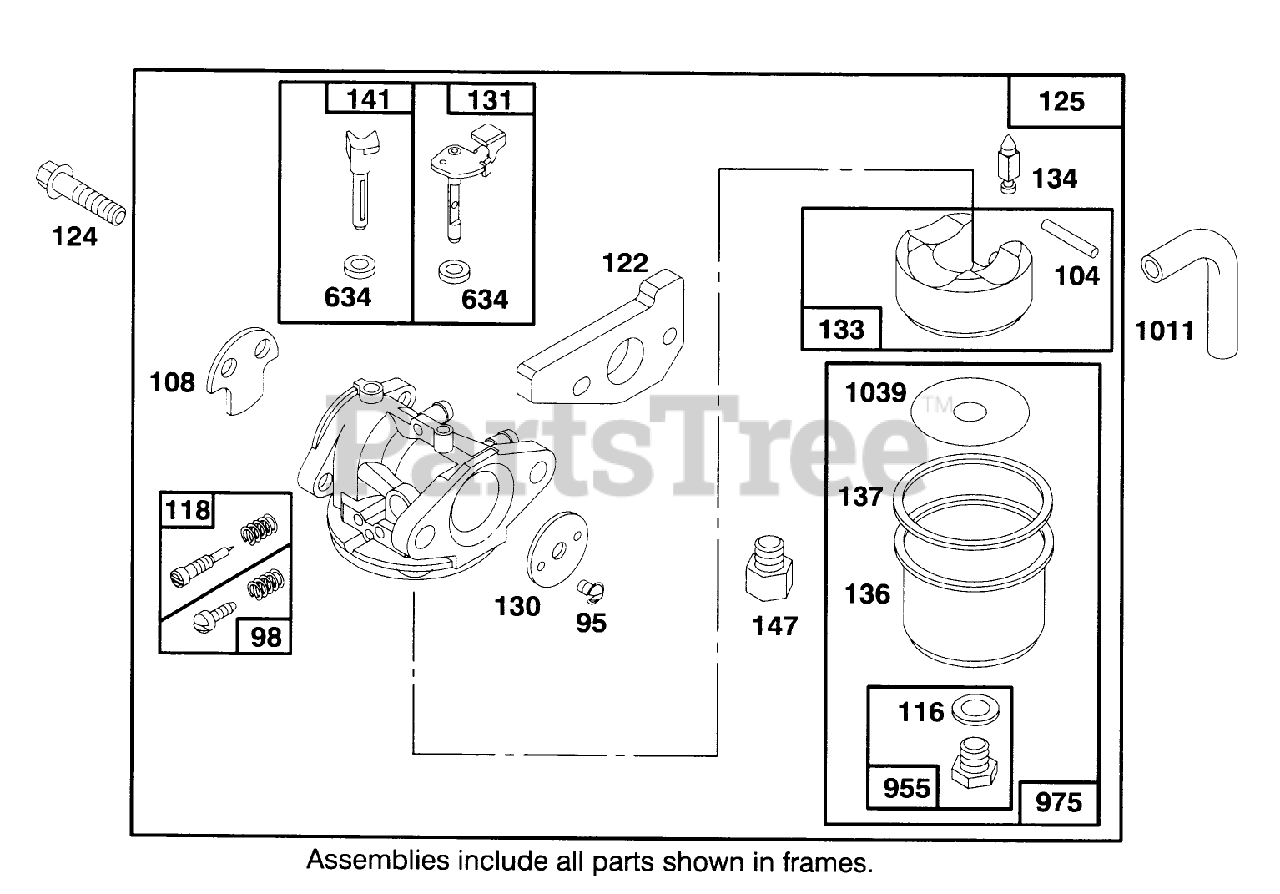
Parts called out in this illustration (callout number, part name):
98	IDLE ADJUSTING SCREW
108	Valve-Choke
116	SEALING GASKET
118	VALVE KIT - NEEDLE
122	ADAPTER ASSEMBLY
124	HEX HEAD SCREW
130	THROTTLE VALVE
133	FLOAT-CARBURETOR
134	VALVE-FLOAT
137	FLOAT BOWL GASKET
147	JET ADAPTER
1011	VENT TUBE
1039	FLOAT LIMITER
